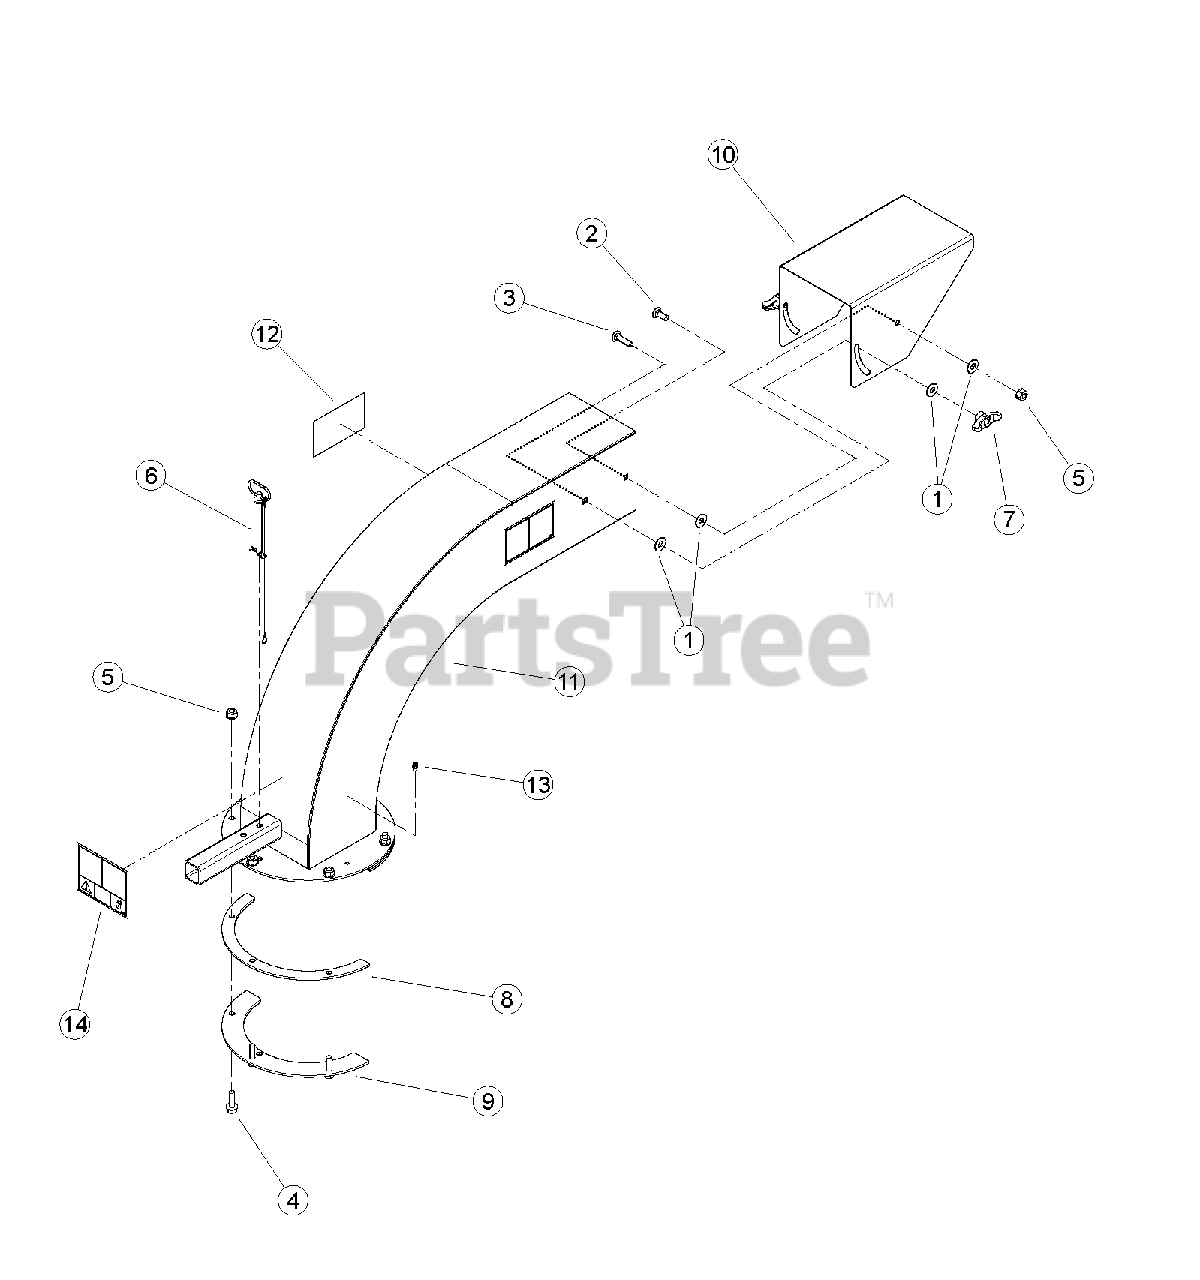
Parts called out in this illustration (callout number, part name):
1	WASHER, 3/8" FLAT ZP
2	BOLT, 3/8 X 1" GR5 CRG NC ZP
3	BOLT, 3/8 X 1-1/2"GR5 CRG NC ZP
4	BOLT, 3/8 X 1-1/4 FLANGE NC
5	NUT, 3/8-16 NYLOCK FLANGE
6	PIN, 3/8 X 4.25" DISCHARGE
7	KNOB, 3/8-16 UNC FEMALE TEE
8	RING, DISCHARGE SPACER
9	RING, DISCHARGE CLAMP
10	CAP, ORCHARD DISCHARGE
11	ASSEMBLY, ORCHARD DISCHARGE W/ DECALS
12	DECAL, DISCHARGE ISO
13	FITTING, 1/4 SELF-TAP GREASE
14	DECAL, DISCHARGE DEBRIS & LOCK
